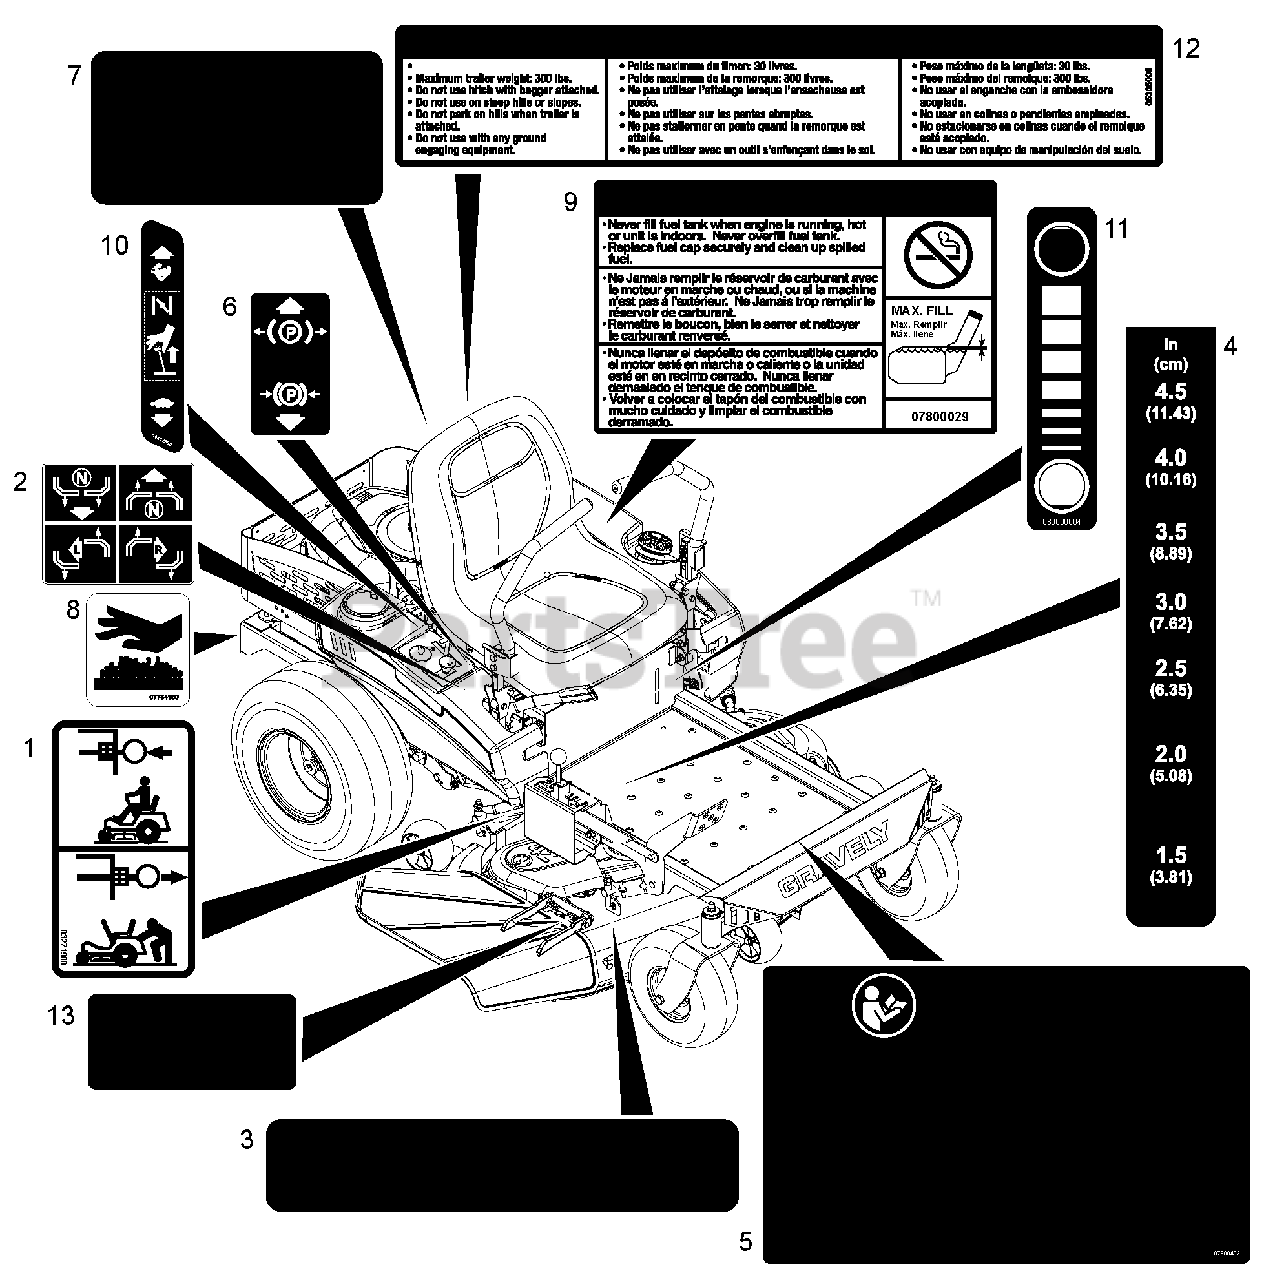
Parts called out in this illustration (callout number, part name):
1	Decal, Transmission Disconnect
2	Decal, Instructional Steering
3	Decal, Safety – Mower Deck
4	Decal, Cut Height
5	Decal, Safety – Main
6	Decal, Parking Brake Lever
7	Decal, Safety – Guarding
8	Decal, Hot Surface
9	Decal, Fuel Warning
10	Decal, Throttle/Choke Combo
11	Decal, Fuel Level
12	Decal, Trailer Hitch (915328)
13	Decal, Safety – Deck Guarding
